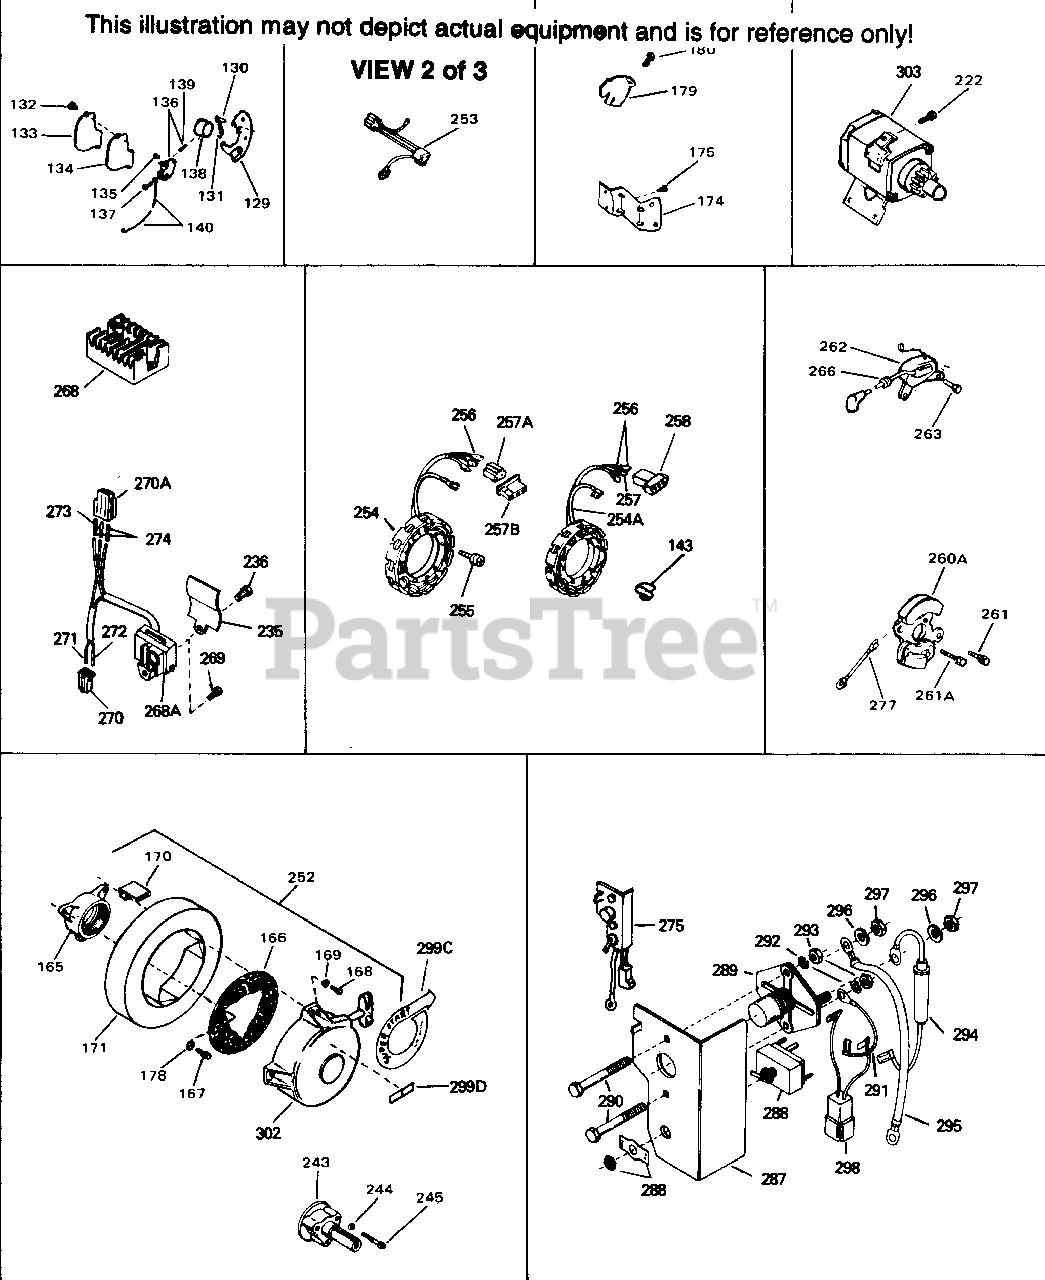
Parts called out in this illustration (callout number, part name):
178	Lockwasher
178	Washer, Flat 1/4 (Use as required)
180	Screw, 8-18 x 7/16" (Use as required)
222	Screw,5/16-18 x 11/16" Use w/33835 st r.motor
222	Screw, 5/16-18 x 7/8" Use w/32817 st r.motor
235	Plate, Cover Use as required to cover regulator mounting hole in blower ho using
236	Screw, 10-16 x 3/8" (Use as required)
252	Rewind Starter Kit (Incl. 165, 166, 1 67, 168, 169 & 291) (Use as required)
253	Harness Assy., Adapter Use as requir ed
254A	Alternator Coil (20 Amp) Incl. 256,25 7 ,258
255	Screw, 10-32 x 1-1/8"
256	Terminal
257	Terminal
257B	Flat Connector (Female terminals) As req.
258	Connector, Flat
266	Grommet, Lead wire
268	Regulator (20 Amp) Incl. 268A, 269 & 298
275	Starter Switch Kit (Incl. 287-298) As req.
303	Electric Starter Motor (12 Volt) NOTE : The 32817 and 33835 starter motors are used interchangeably on the se m odels. Refer to service numberstampe d on end cap of motor, or on decal fo r identification. Refer to Division 5, Section D for breakdo
